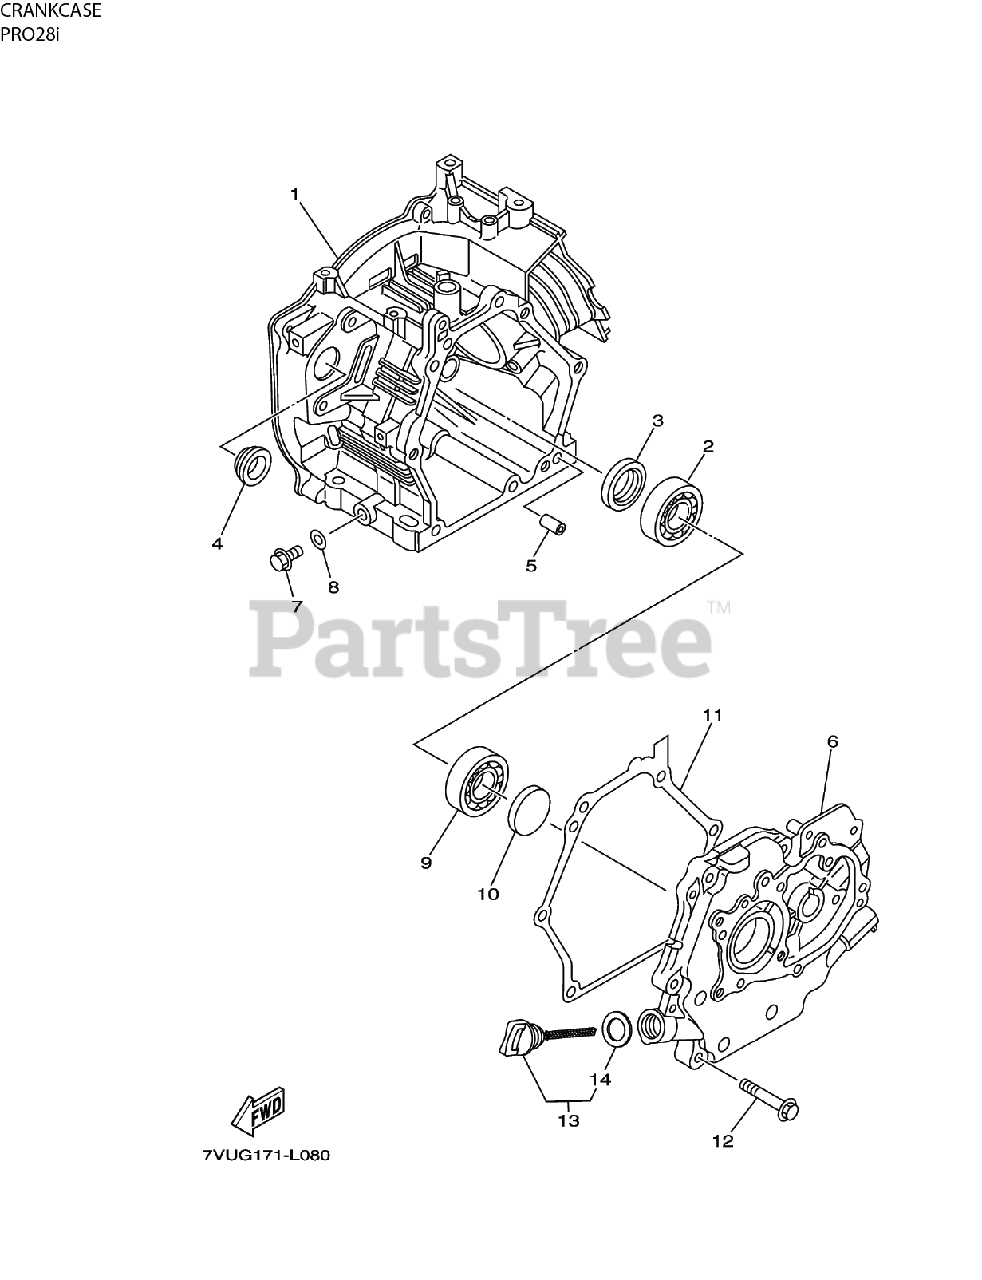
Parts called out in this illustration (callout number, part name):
1	CRANKCASE
3	SEAL, OIL
5	PIN, DOWEL
6	PLATE, CLOSURE & BEARING
7	PLUG - BOLT, FLANGE
8	WASHER, GASKET
11	GASKET, CRANKCASE COVER
12	SCREW - PAN HEAD
13	DIPSTICK - PLUG, OIL LEVEL
14	O-RING, GASKET
